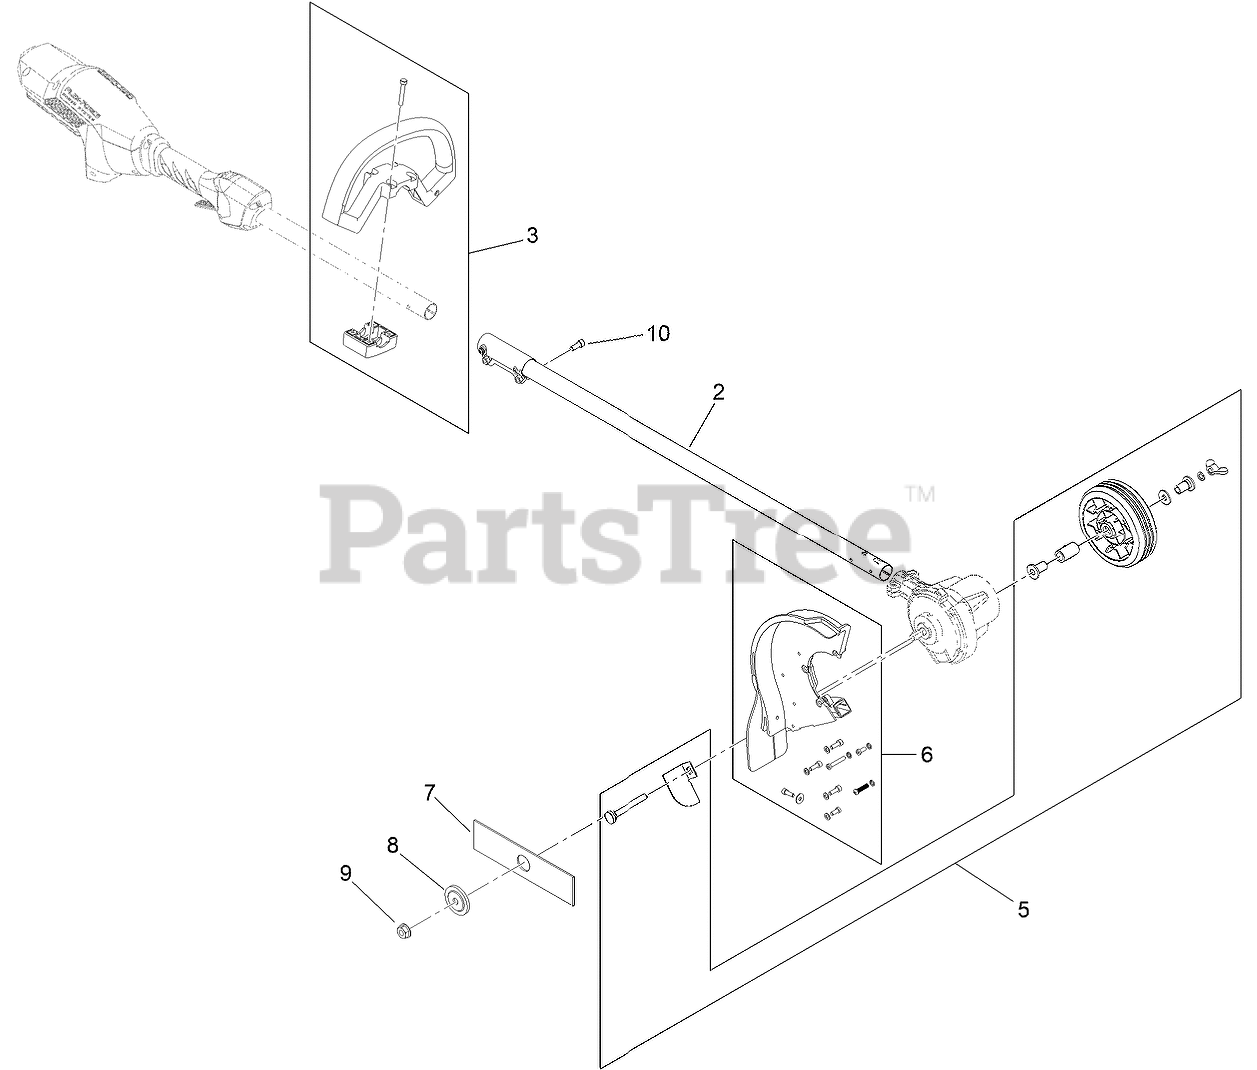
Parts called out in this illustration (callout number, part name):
2	SHAFT ASM
3	HANDLE-TRIMMER
5	WHEEL ASM
6	GUARD ASM
8	WASHER
10	SCREW-ROD
